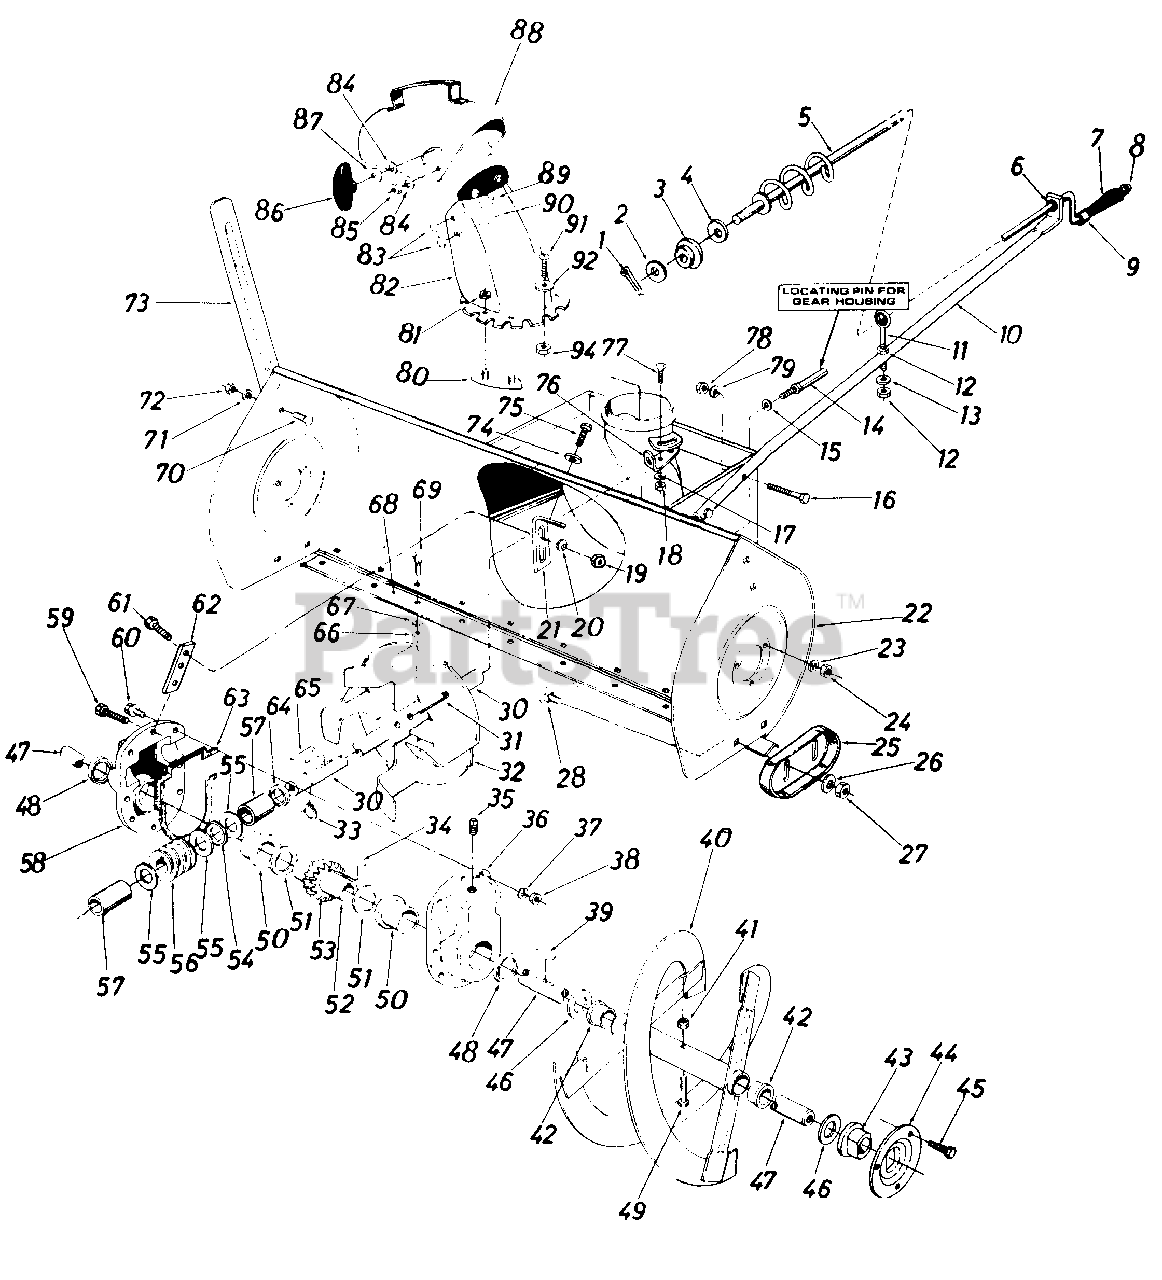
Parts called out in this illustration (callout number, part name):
1	Cotter Pin
2	Fl.-Wash. .39" I.D. x .62" O.D.
3	Plastic Bushing
4	Fl. Wash. .385 I.D. x .62" O.D.
5	Chute Crank Ass'y.
6	Plastic Bushin
7	Knob Ball 3/8 Dia. Hole
8	Push Nut 3/8" Rod
9	Spacer.385 I.D. x .50" I.D.
10	Chute Crank Support Tubing
11	Eyebolt
12	Hex Nut 5/16 18 Thd.*
13	Bell. Wash. .345" I.D. x .88" O.D.
14	Stud 3/8-16 x 2.75" Lg.
15	Bell.-Wash. .400" I.D. x.88" O.D.
16	Hex Bolt 3/8-24 x 1.25" Lg.*
17	Bell.-Wash. .345" I.D. x .88" O.D.
18	Hex Nut 5/16-18 Thd.*
19	Hex Nut 1/4-28 Thd.
20	Bell.-Wash. .265" I.D. x .75"O.D.
22	45" Snow Blower Housing Ass'y.
23	L.-Wash. 5/16" I.D.*
24	Hex Nut 5/16-18 Thd.*
25	Slide Shoe
26	5ell.-Wash. .400" I.D. x .88"O.D.
27	Hex Jam Nut 3/8-16 Thd.
28	Carriage Bolt 3/8-16x .62" Lg.*
30	Blower Axle .875" Dia. x 14.75" Lg.
31	Spring Pin Spir. 5/16" Dia. x 1.75" Lg.
34	#91 Woodr-Key 1/4 x 3/4" Dia. (HDN)
35	Vent Plug
36	Comp. Gear Hsg. Half-L.H.
37	Spr.-Wash. .32" I.D. x .62" O.D.
38	Hex Ins. L.-Nut 5/16-18 Thd.
39	#91 Woodr-Key 1/4 x 3/4" Dia. (HDN)
41	Hex Ins. L.-Nut 5/16-18 Thd.
42	Plastic Bushing
43	Flange Brg. w/flats 1" I.D.
44	Bearing Housing
45	Hex Sems Bolt 5/16-18 x .75" Lg.*
46	Fl.-Wash. 1.00" I.D. x 1.75" O.D.
47	Spiral Axle
48	Flange Bearing 1.503" I.D.
49	Shear Bolt 5/16-18 x 1.75" Lg.
50	Oil Seal 1.50" I.D.
51	Fl.-Wash.1.50" I.D. x 2.00" O.D.
52	Worm Gear Shaft
53	Double Threaded Worm Gear L.H.
54	Thrust Bry. .88" I.D. x 1.44" O.D.
55	Fl. Wash. .88" I.D. x 1.4" O.D.
56	Double Threaded Worm - L.H.
57	Sleeve
58	Complete Gear Hsg. Half - R.H.
59	Hex Bolt 5/16 18 x 1.25" Lg.*
60	Hex Bolt 5/16-18 x 1.0" Lg. (Grade 5)
61	Hex Bolt 1/4-18 x .75" Lg.
62	Gear Housing Support Plate
63	Rubber Gasket
64	Oil Seal - .875" I.D.
65	#9 Hi-Pro Key 3/16 x 3/4" Dia. (HT.)
66	Hex Nut 5/16-18 Thd.*
67	L.-Wash. 5/16" I.D.*
69	Carriage Bolt 5/16-18 x 1.00" Lg.*
70	Carriage Bolt 5/16-18 x .62" Lg.*
71	L.-Wash. 5/16" I.D.*
72	Hex Nut 5/16-18 Thd.*
73	Guide Blade
74	Bell.-Wash. .345" I.D. x .88" O.D.
75	Hex Wash. Hd. AB Tap Scr 5/16 x .75" Lg.
77	Carriage Bolt 5/16-18 x .75" Lg.*
78	Hex Ins. L.-Nut 3/8-2 Thd.
79	L.-Wash. 3/8" I.D.*
80	Chute Flange Keeper
81	Hex Cent. L.-Nut 1/4-20 Thd.
82	Chute Ass'y. w/Chute Guard
83	Fl.-Wash. .285" I.D. x 1.25" O.D.
84	Bell.-Wash. .345" I.D. x .88" O.D.
85	Hex Cent. L.-Nut 5/16-18 Thd.
86	Knob Handle
87	Bell.-Wash. .345" I.D. x .88" O.D.
88	Top Chute Ass'y.
89	Carriage Bolt 5/16-18 x 1.00" Lg.*
90	Carriage Bolt 5/16-18 x .62" Lg*
91	Truss Nlach. Scr. 1/4-20 x .50
92	FI .-Wash . .285" I . D. x 1.25" O.D.
94	Hex Cent. L-Nut-1/4-20 Thd.
